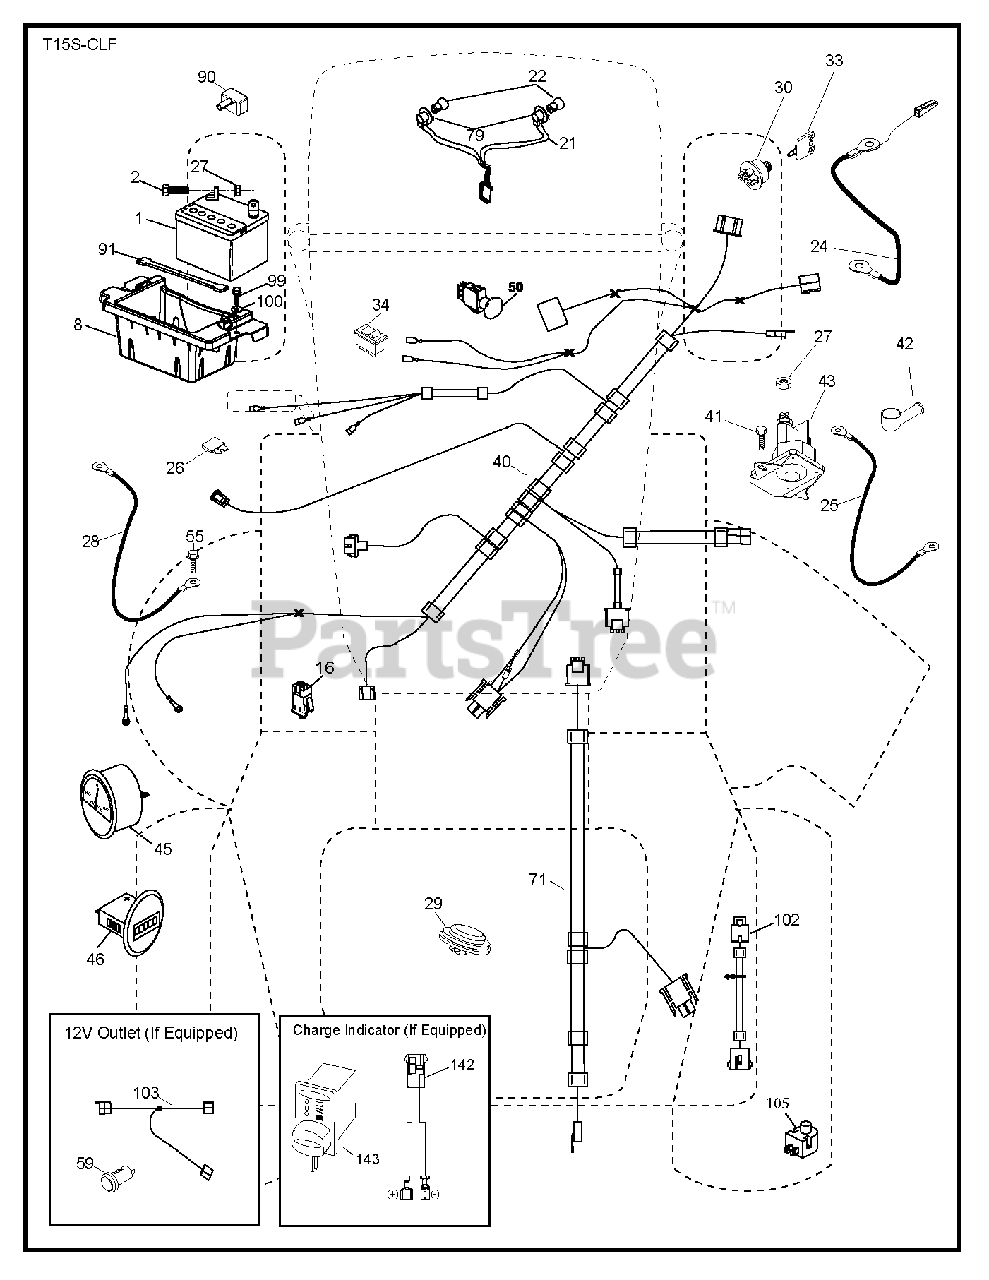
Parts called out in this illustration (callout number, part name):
1	Battery, Dry 30 Amp
2	BOLT.HEX.1/4.X.3/4.DICHROMATE
8	TRAY.BATTERY.FRONT.CARB
16	SWITCH INTERLOOK PUSH-IN
21	HARNESS.LIGHT W/4152J BULBS
24	CABLE.FRBATT.W/WIRE.8GA.8
25	CABLE.STARTER.8GA.17.5
26	FUSE 20AMP
27	NUT
28	CABLE.GROUND.21"BLK.8GA.90T
29	SWITCH.SEAT.DELTA.OPC.
30	SWITCH.IGN.DELTA.W.LGH.ROS
33	KEY.CHAIN.BLISTER.PACK.GEN.USA
40	HARNESS.IGN.DASH.W/112V.PORT
41	SCREW
42	TERMINAL COVER
43	SOLENOID.W/BRASS.PLUNGER
45	GAUGE.AMMETER.SILVER/WHITE
46	GAUGE.HOUR.METER.SILVER/WHITE
50	RB PTO.SWITCH.8 TERMINAL.BLACK
55	SCREW 5/16"
59	OUTLET.12-VOLT
71	HARNESS-CHASSIS SUB
79	BULB HOLDER ASM.
90	COVER.TERMINAL.BATTERY
91	STRAP.BATTERY.MOUNT.FRONT(2 2)
99	SCREW HEXWSHR 1/4-20X3/4
102	HARNESS PIGTAIL PCH TEX ROS
103	HARNESS.PIGTAIL.12V.OUTLET.
105	REVERSE SWITCH
142	CHARGE.PORT.PIGTAIL HARNESS
143	CHARGE.PORT
